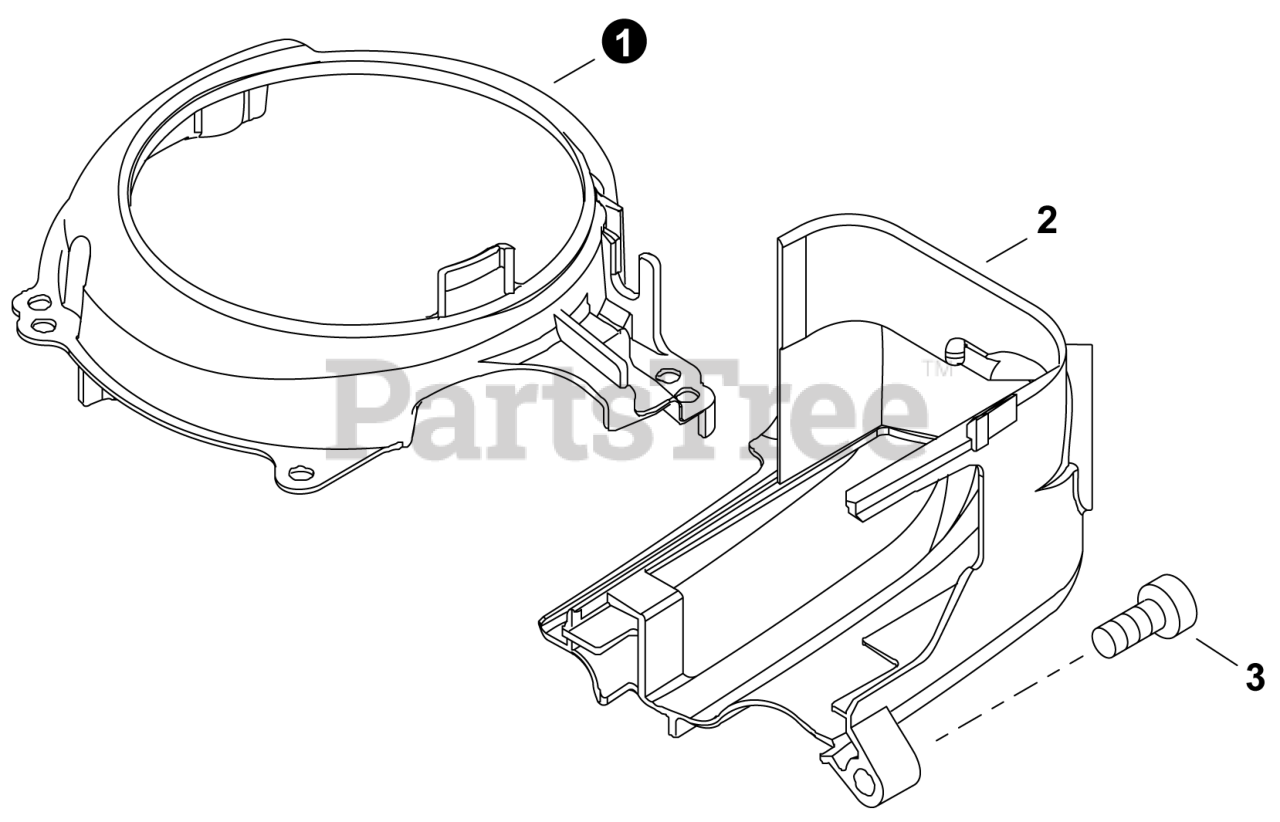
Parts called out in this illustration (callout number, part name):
1	COVER, FAN
2	COVER, ENGINE
3	BOLT, TORX 5x16
